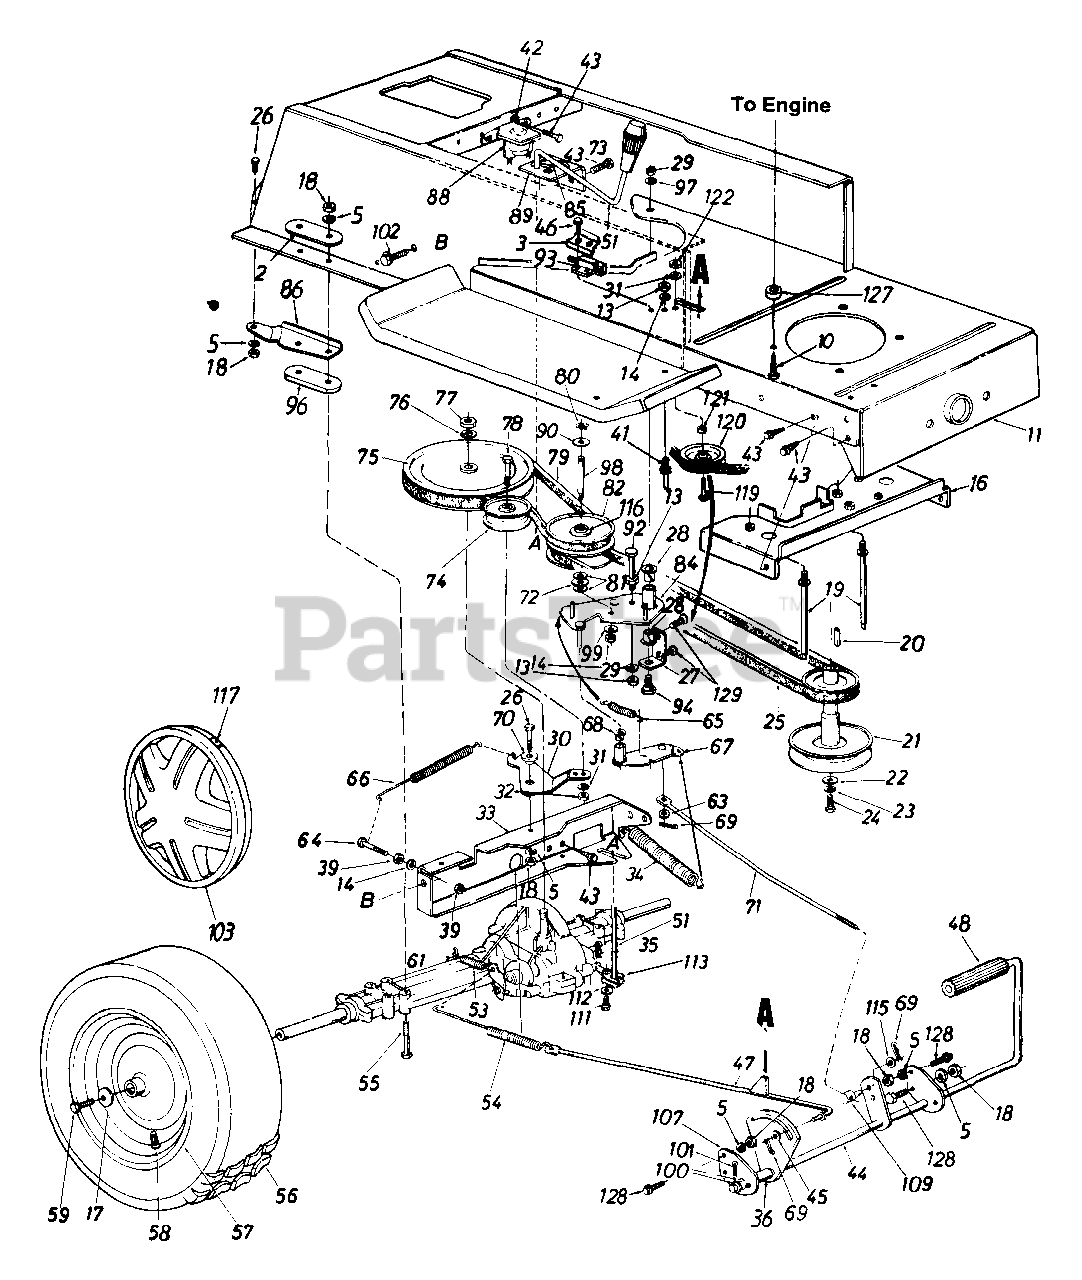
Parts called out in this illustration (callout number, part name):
3	Switch Plate
5	L-Wash. 5/16" I.D.
10	Hex L-Wash. Tap Scr. 3/8-16 x 1.5" Lg. (B&S)
11	Lower Frame Ass'y.
13	Hex Nut 1/4-20 Thd.
14	L-Wash. 1/4" I.D.
16	Belt Guard Brkt. Ass'y.
17	Bell-Wash..345" I.D. x .88"
18	Hex Nut 5/16-18 Thd.
19	Belt Guard Stud 3.6" Lg.
20	Sq. Key 1/4" x 1/4" x 2.00"
21	Engine Pulley
22	Fl-Wash. 7/16" I.D. x 1.25"
23	L-Wash. 7/16" I.D.
24	Hex Bolt 7/16-20 x 1.50" Lg.
25	Variable-Speed Belt
26	Hex Bolt 5/16-18 x .75" Lg.
27	Bearing Shaft Bracket Ass'y.
28	Flanged Nyliner Brg. 5/8" I.D. x .88" Lg.
29	Hex Nut 3/8-24 Thd.
31	L-Wash. 3/8" I.D.
32	Hex Nut 3/8-24 Thd.
35	Inter. Cotter Pin
36	Spacer .63" I.D.
39	Hex Nut 1/4-28 Thd.
41	Belt Guard Pin
42	Ext. L-Wash. 1/4" I.D.
43	Hex Wash. Hd. S-Tap Scr. 1/4-20 x .50" Lg.
46	Truss Mach. Scr. B-Tap Scr. #10 x .5" Lg.
47	Brake Rod Ass'y.
48	Foot Pad
51	Shift Lever Ass'y.
53	Ext. Spring .38" O.D. x 2.5"
54	Ext. Spring 7.08" Lg.
55	Hex Bolt 5/16-18 x 3.5" Lg.
57	Wheel Rim Only
58	Air Valve (Service Only)
59	Hex Bolt 5/16-24 x .75" Lg.
61	Brake Return Spring Anchor
63	Fl-Wash..34" l.D. x .68" O.D.
64	Hex Bolt 1/4-28 x 1.25" Lg.
65	Ext. Spring
66	Ext. Spring .62" O.D. x 6.12"
68	Flanged Bearing
69	Cotter Pin 3/32" Dia.
70	Shoulder Spacer .27" Lg.
71	Speed Control Link
72	Truss Bearing .56 Dia. x 1.25"
73	Shift Knob
74	Fl-Idler Pulley 3.25" x .75"
75	"V" Pulley
76	Bell-Wash..56" I.D. x 1.125"
77	Hex Jam Nut 5/16-18 Thd.
78	Hex Bolt 3/8-24 x 1.75" Lg.
79	Variable Speed Belt
80	Snap Ring .56" Dia.
81	Fl-Wash.
82	Variable Speed Pulley Ass'y. 5" O.D.
90	Teflon Washer .565" I.D.
92	Hex Bolt 1/4-20 x 3.5" Lg.
93	Safety Switch (Clutch)
94	Shld. Bolt 3/8-24 x 3.12" Lg.
96	Transaxle Spacer
97	Bell-Wash..38" I.D. x .88"
98	Shaft .56" Dia. x 3.875" Lg.
99	Bell-Wash..39" I.D. x 1.12"
100	Fl-Wash..64" I.D. x .94"
101	Cotter Pin 1/8" Dia. x 1.25"
102	Hex Wash. Hd. Scr. 5/16-18 x .62" Lg.
103	Hub Cap (Gray)
111	Hex Bolt 1/4-28 x .50" Lg.
112	Bell-Wash..265" I.D. x .75"
113	Shift Lever Link Ass'y.
115	Fl-Wash..385" I.D. x .62"
116	Needle Brgs.
117	Spring Clip
119	Hex Bolt 3/8-16 x 1.25" Lg.
120	Fl-Idler w/Flanges 2.75" O.D.
121	Fl-Wash..39" I.D. x 1.12" O.D.
122	Hex Nut 3/8-16 Thd.
127	Spacer 5/16" I.D. (B&S Vanguard Only)
128	Hex Wash. TT-Tap Scr. 5/16-18 x .75" Lg.
129	Hex Wash. AB-Tap Scr. 5/16-18 x .75" Lg.
